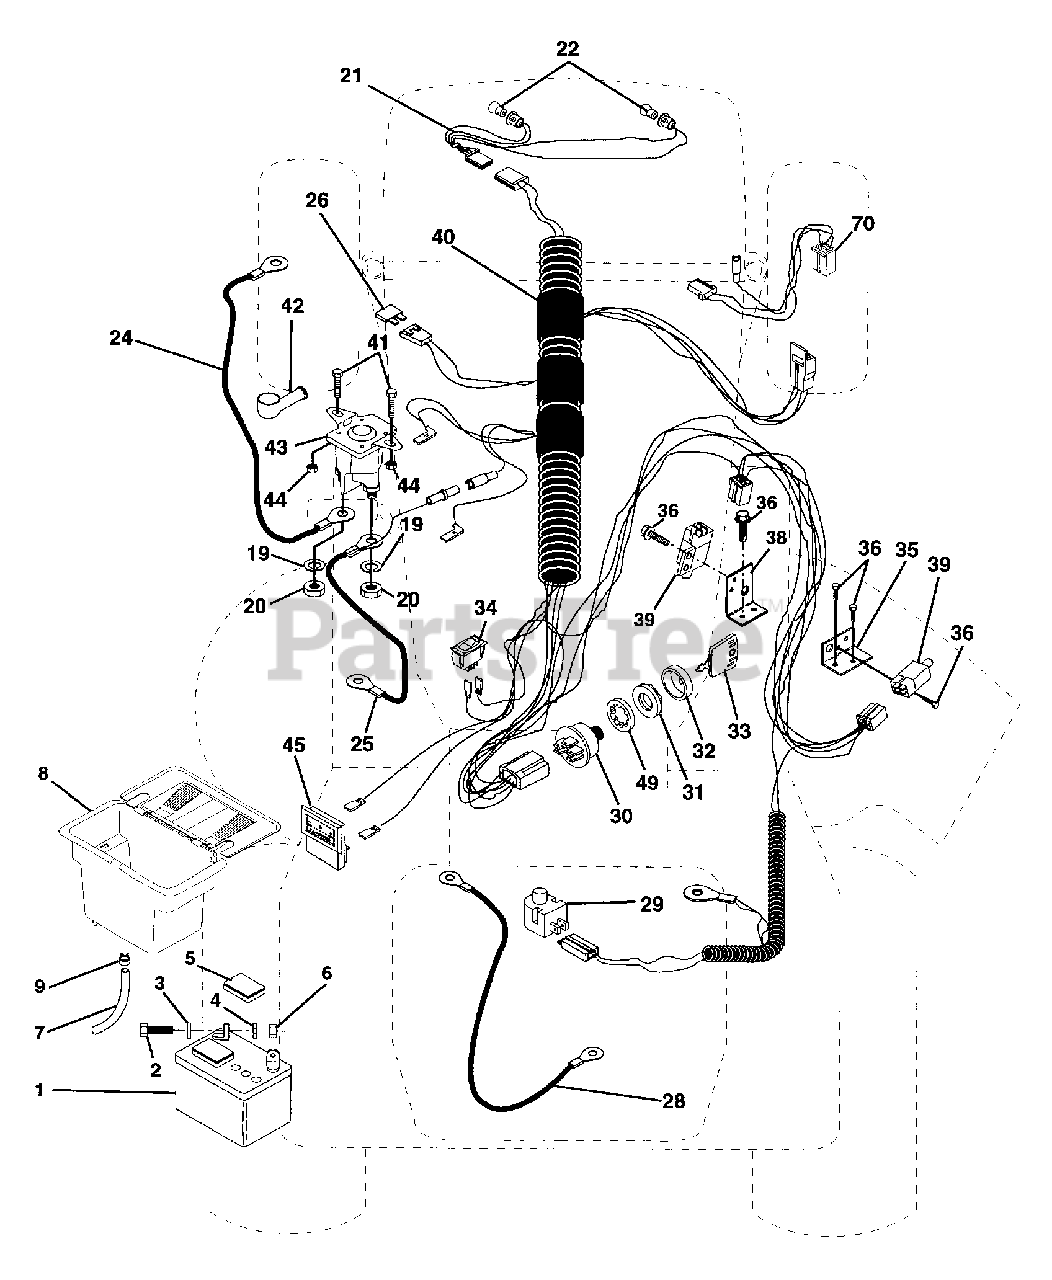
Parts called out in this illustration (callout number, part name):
2	BOLT LT
3	WASHER
4	LOCKWASHER
5	"CAP,BATTERY "
7	TUBE T
9	HOSE CLAMP T
20	NUT
21	"HARNESS,LIGHT SOC"
22	HEADLAMP BULB
25	CABLE.BTRY.6GA.RD
26	FUSE HYT
28	CABLE T
29	SWITCH SEAT
32	COVER KEY SWITCH
33	KEY MLD CRAF DELT
34	SWITCH LT
35	BRACKET LT
36	SCREW
38	BRACKET SWITCH IN
39	SWITCH INTERLOCKT
40	HARNESS.IGN.DASH.
41	BOLT.HX.1/4-20
44	NUT
49	LOCKWASHER
70	HARNESS ENG DUAL
